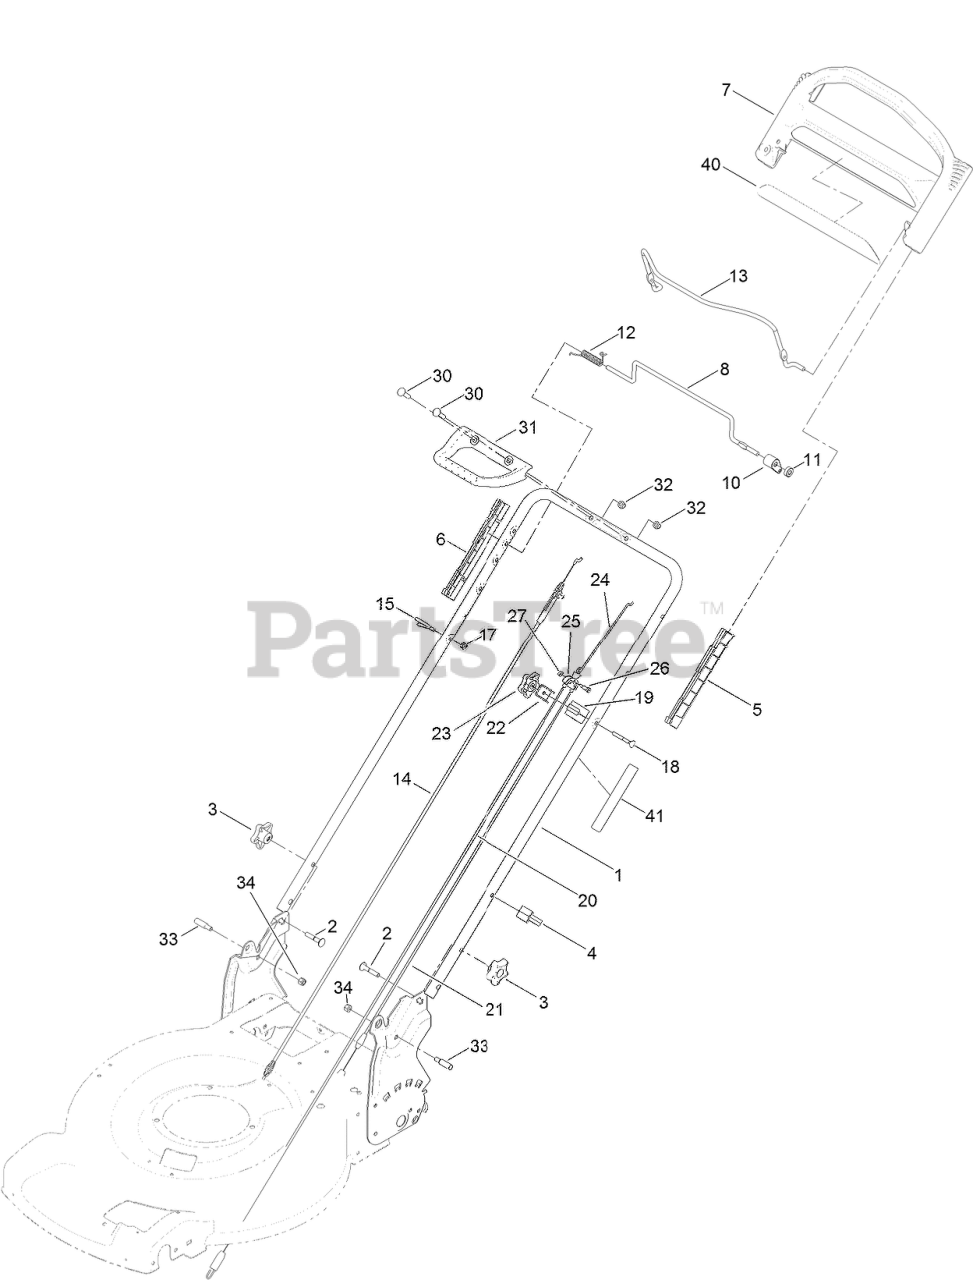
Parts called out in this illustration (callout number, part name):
2	SCREW-CARR
3	KNOB-HANDLE
4	GUIDE-CABLE
5	GUIDE-LH
6	GUIDE-RH
7	HANDLE-CONTROL
8	BAR-CONTROL, TRACTION
10	LEVER-TRACTION
11	SPACER
12	Spring-Torsion
13	BAIL-BRAKE
14	CABLE-BRAKE
15	GUIDE-ROPE
17	NUT-LOCK, NI
18	SCREW-HANDLE
19	MOUNT-CABLE, TRACTION
20	CABLE-TRACTION, FRONT
21	CABLE-TRACTION, REAR
22	CLAMP-CABLE
23	KNOB-HANDLE, LOCKING
24	LINKAGE-EQUALIZER
25	YOKE-CABLE
26	SCREW-SHOULDER
27	NUT-LOCK, NI
30	BOLT-CARRIAGE
31	HANDLE-ASSIST, TRACTION
32	NUT-ACORN
33	BOLT-SHOULDER
34	NUT-LOCK, NI
40	DECAL-DRIVE, AUTOMATIC
41	DECAL-TRACTION, ADJUST
